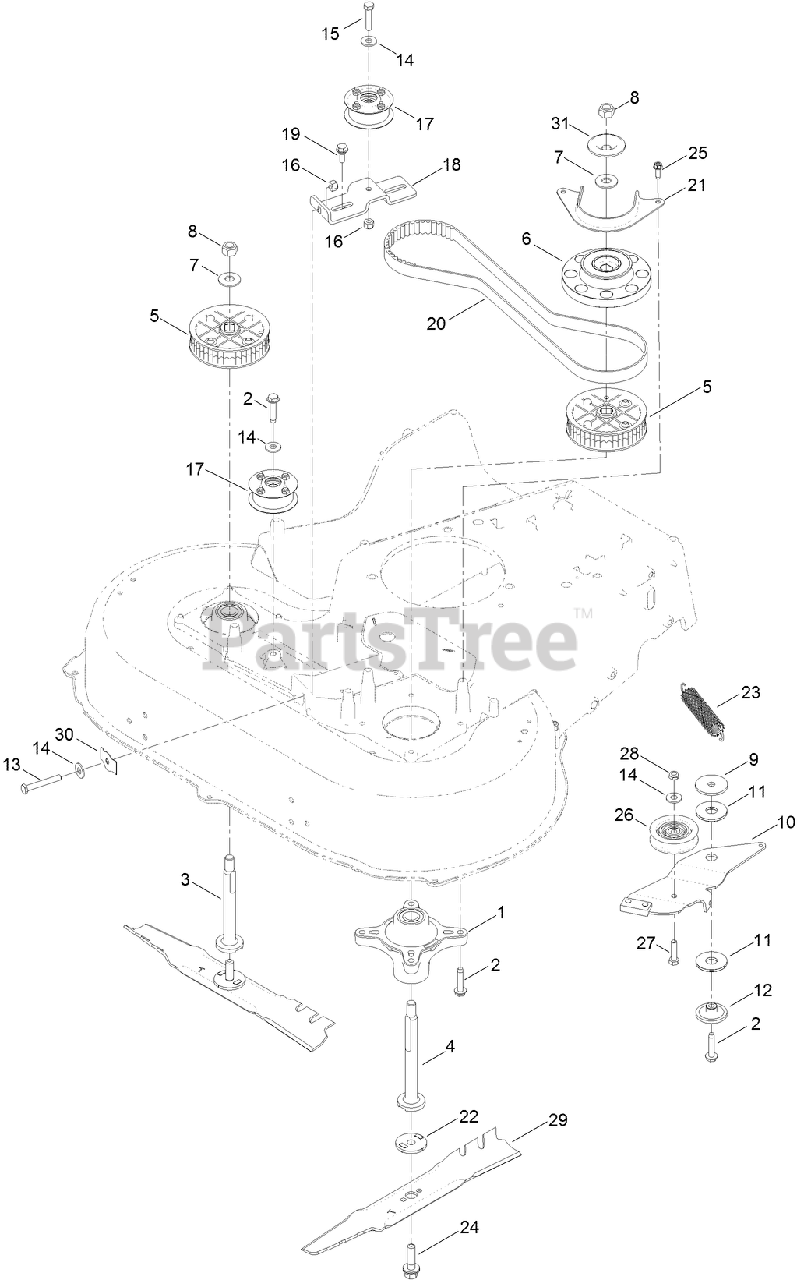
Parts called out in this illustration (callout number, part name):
1	SPINDLE ASM
3	SHAFT-SPINDLE
4	SHAFT-SPINDLE
5	SPROCKET
6	PULLEY-BRAKE, SPINDLE
7	WASHER-SPRING
8	NUT-HEX
9	WASHER-REBOUND
10	ARM-BRAKE
11	WASHER-FRICTION, COMPOSITE
13	BOLT-TAP, HH
14	WASHER-FLAT
15	SCREW-HH
16	NUT-LOCK, NI
18	BRACKET-IDLER
19	SCREW-SHOULDER,HWH
20	BELT-SYNCHRONOUS
21	GUIDE-BELT, SPINDLE
22	ADAPTER-BLADE
23	SPRING-EXTENSION, BRAKE
24	BOLT-BLADE
25	SCREW-HWHTF
26	PULLEY-IDLER
27	SCREW-HH
28	NUT-LOCK, NI
29	BLADE-ATOMIC, 15.4 INCH
30	SPRING-FLAT
31	WASHER-CUP
